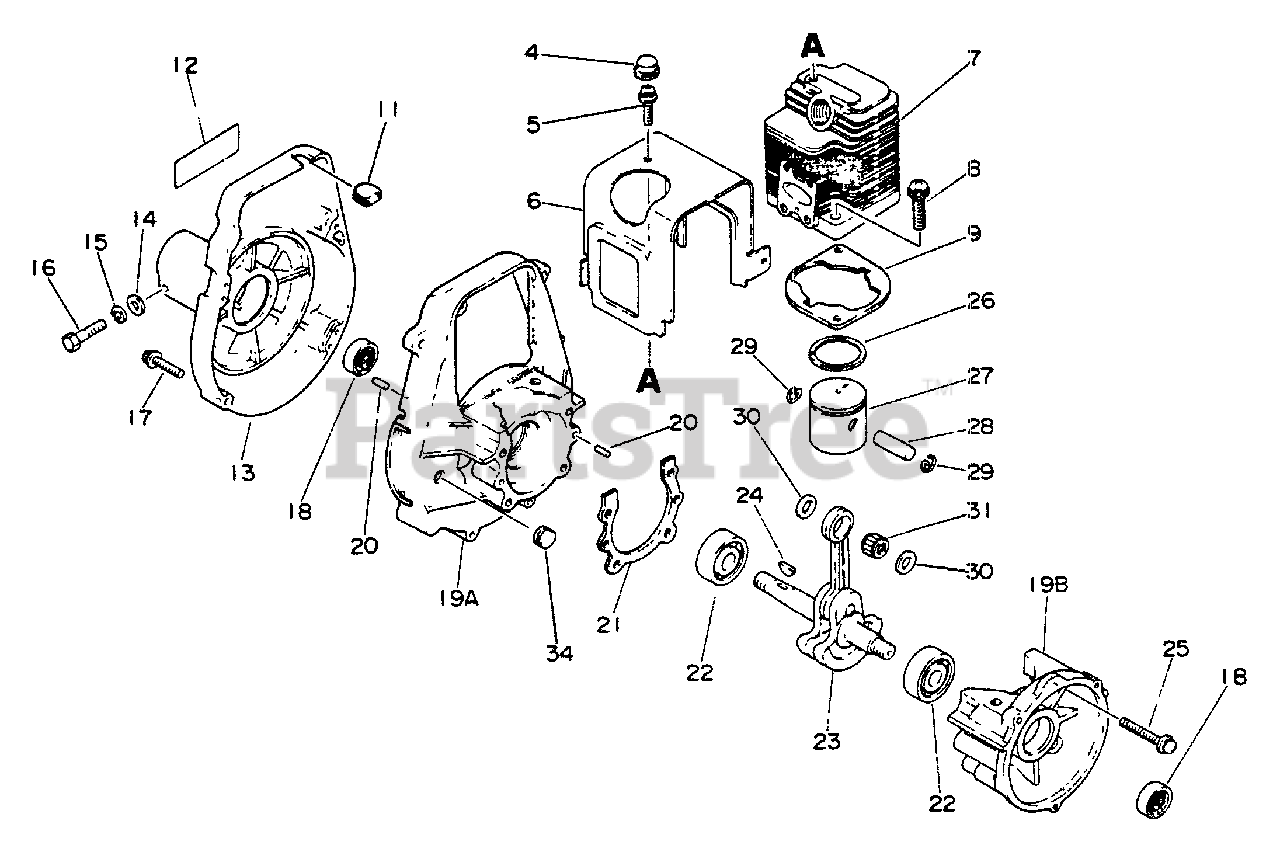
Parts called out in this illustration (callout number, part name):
5	SCREW - 5X10
6	SHIELD, CYLINDER
7	CYLINDER
8	SCREW - 6X20
9	GASKET, CYLINDER
11	PLUG
12	LABEL - MODEL
13	COVER, FAN - ORANGE
14	WASHER - 5
15	LOCKWASHER - 5
16	BOLT - 5X25
17	SCREW - 4X20
18	SEAL, OIL
19	CRANKCASE KIT
19A	CRANKCASE KIT
19B	CRANKCASE KIT
20	PIN - LOCATING
21	GASKET, CRANKCASE
22	BEARING, BALL - 6201
23	CRANKSHAFT ASSY
25	SCREW - 5X30
26	RING, PISTON
27	PISTON
28	PIN, PISTON
29	RING, RETAINING
30	SPACER, PISTON
31	BEARING, NEEDLE - 8
34	PLUG
